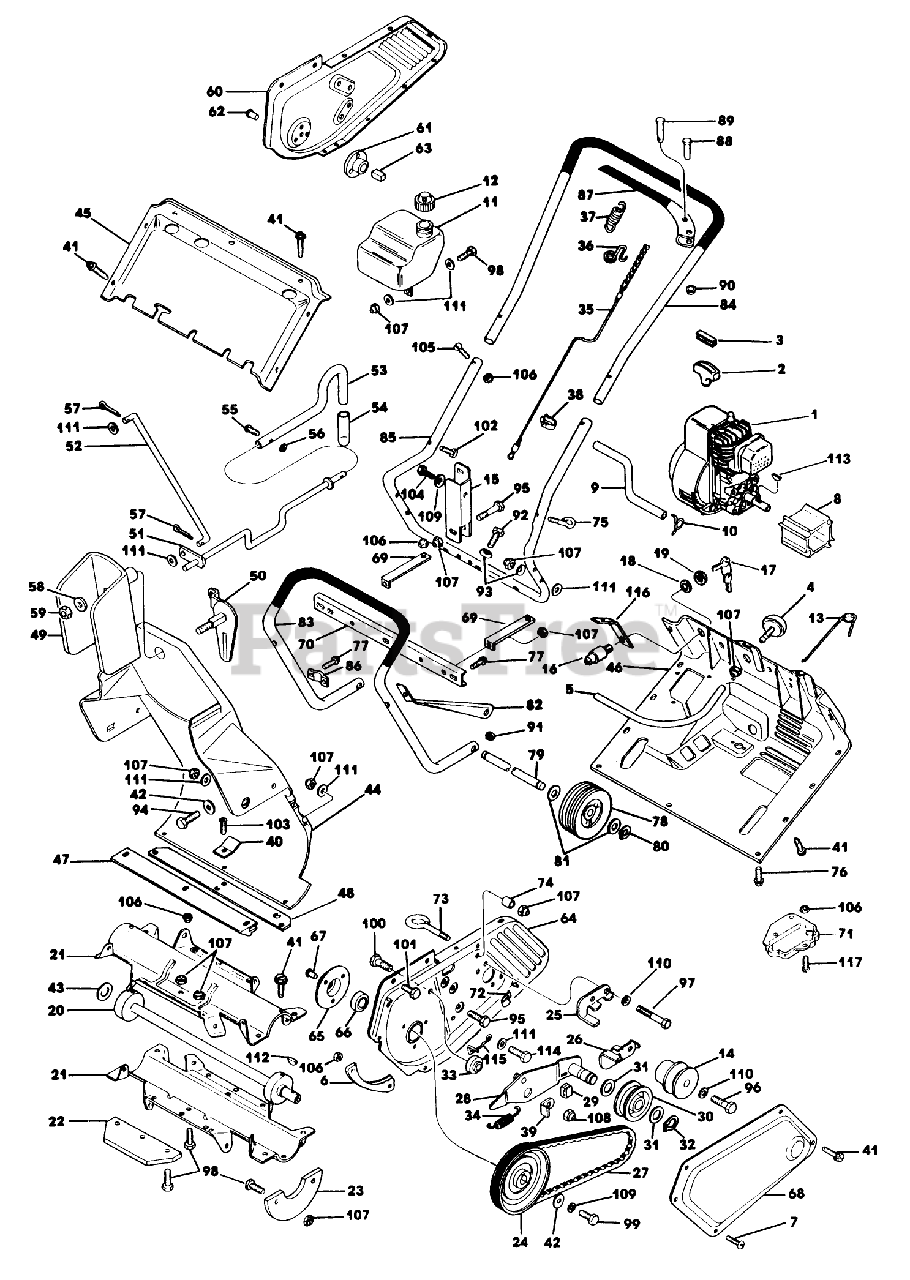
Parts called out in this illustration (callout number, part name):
1	*Engine-Tecumseh 3 H.P.
1	*Engine-Tecumseh 3 H.P. Elec. start
3	CLIP-STARTER
4	PRIMER ASSEMBLY
7	SCREW
10	CLAMP
12	GAS CAP ASM
13	CHOKE WIRE ASM
14	ENGINE PULLEY
20	AUGER SUPPORT AY
21	PLATE-AUGER
22	IMPELLER TIP
23	FLIGHT
24	DRIVE PULLEY AY
25	UPPER BELT GUIDE
27	V-BELT (207159)
28	IDLER ARM ASM
29	SKID BLOCK
31	WASHER
34	BRAKE SPRING
36	CLIP CABLE
37	SPRING - CLUTCH
46	BOTTOM COVER&DECAL
49	VANE-DEFLECTOR
52	CONTROL LINK
59	NUT
66	BEARING - BALL
68	COVER - BELT *B
71	START BLOCK SPACER
77	SCREW
80	SNAP RING
85	FRAME TUBE
87	LEVER ASM
89	PIN-CLEVIS
100	SCREW
101	SCREW
103	SCREW
106	NUT E
107	NUT-LOCK, CONE
108	NUT
115	FINGER BELT
117	SCREW - PPH
